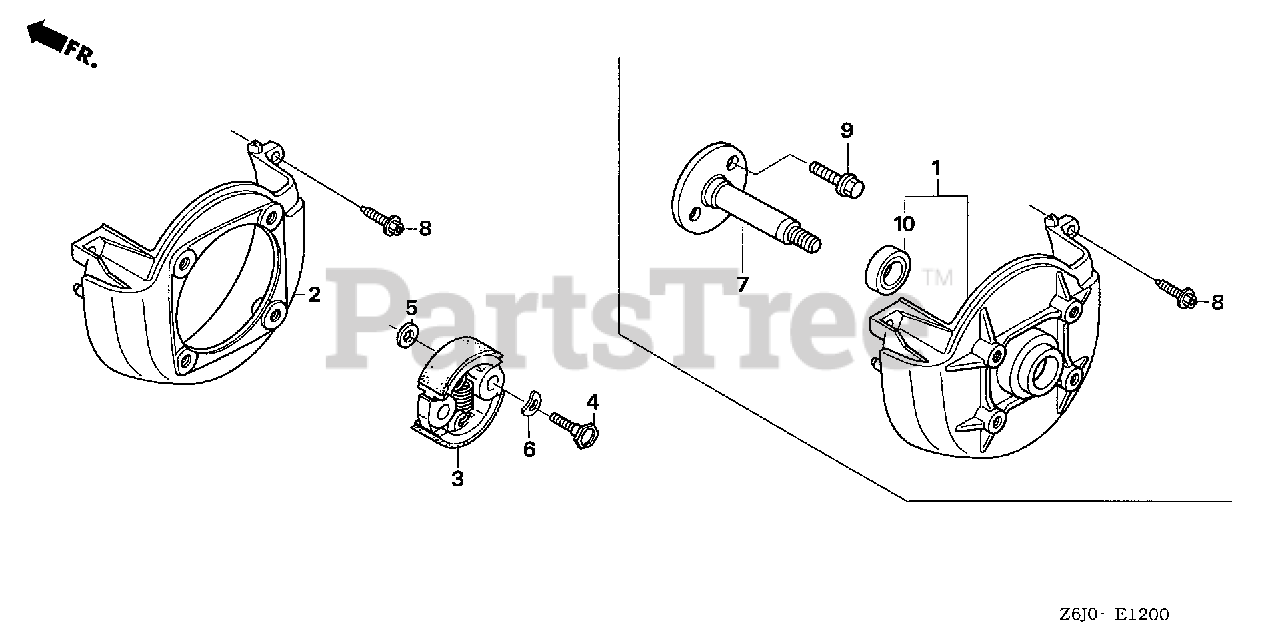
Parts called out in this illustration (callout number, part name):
1	COVER, FAN
7	SHAFT, P.T.O.
8	BOLT, SOCKET (5X20)
9	BOLT, FLANGE (6X22)
10	BEARING, RADIAL BALL (6001UU) (SOURCE: VINTAGE PARTS INC.)
